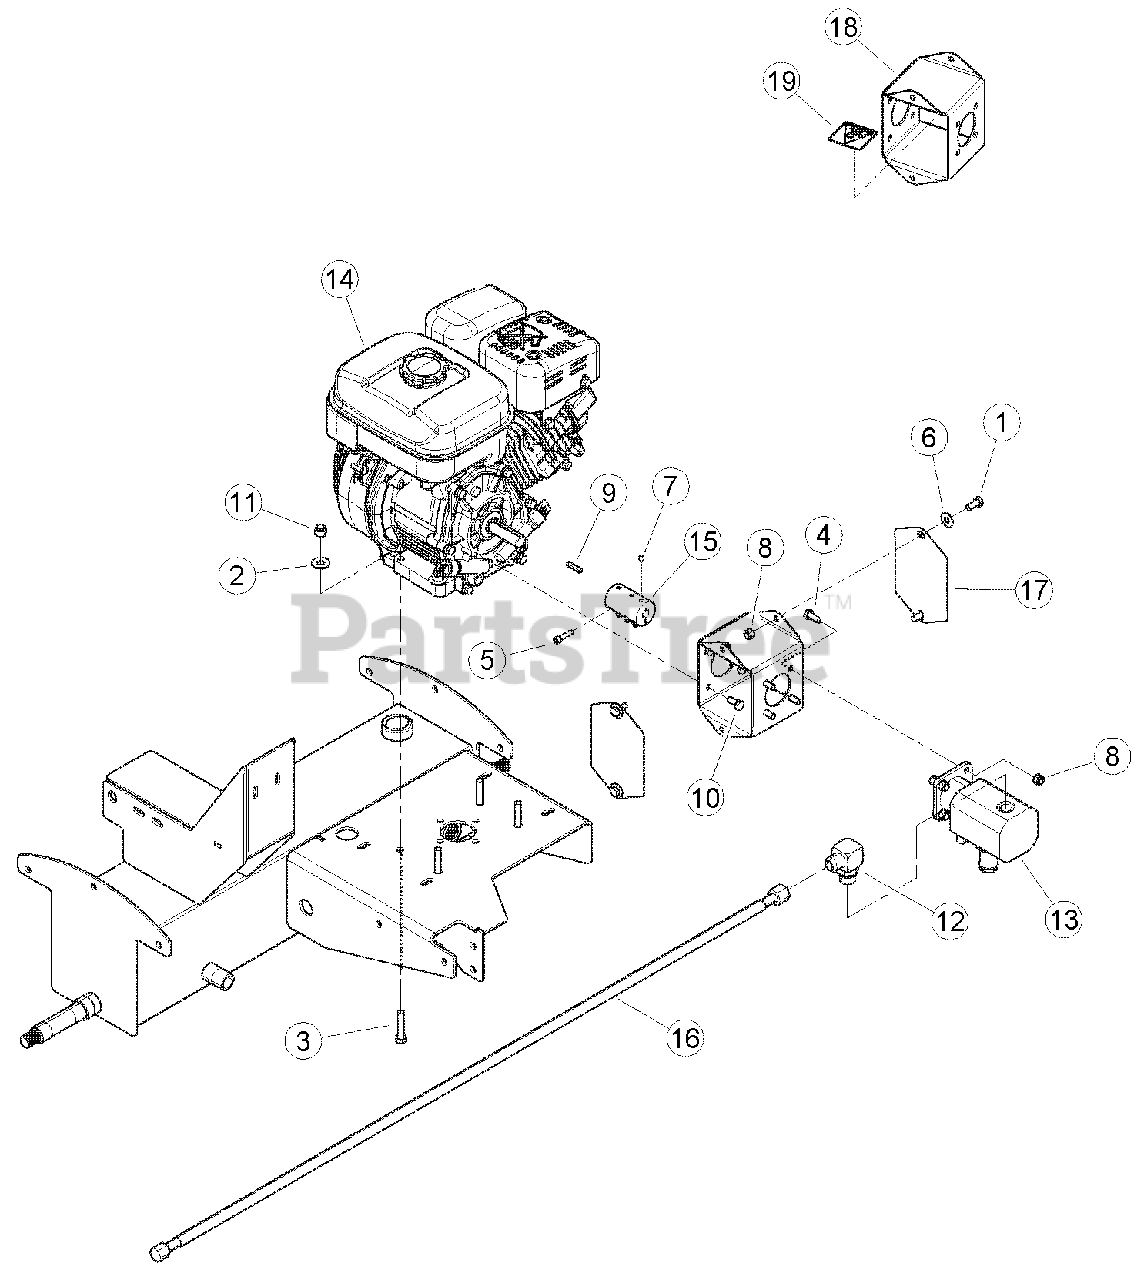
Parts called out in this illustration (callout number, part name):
1	BOLT, 5/16 X 3/4 HEX HD GR5 ZP
2	WASHER, 3/8 FLAT ZP
3	BOLT, 3/8 X 1-3/4 HEX HD GR5 ZP
4	BOLT, 5/16 X 1 HEX HD GR5 NC ZP
5	BOLT, 1/4 X 1 SOC HD CAP SCRW
6	WASHER, 5/16 FLAT ZP
7	SCREW, 1/4-20 X 1/4 KNR CUP SKT SET
8	NUT, 5/16 NE NYLOCK ZP
9	KEY, 3/16 SQUARE X 1 LONG
10	BOLT, 5/16-24 X 3/4 HEX HD GR5 ZP
11	NUT, 3/8 NE NYLOCK ZP
12	ADAPTER, -10 MORING / -10 MJIC 90 DEG.
13	PUMP, LOG SPLITTER 2 STAGE
14	ENGINE, SUBARU SP210 (FOR SERVICE CONSULT ENGINE OWNER'S MANUAL OR YOUR NEAREST AUTHORIZED SUBARU INDUSTRIAL ENGINE DEALER.
15	COUPLER, SPLIT 3/4" TO 1/2" SHAFT
16	HOSE, .50 X 50 -10FJICSW/-10FJICSW
17	PLATE, PUMP MOUNT COVER
18	WELDMENT, PUMP MOUNT, SERVICE PART
19	DECAL, SHIELD DANGER ISO
